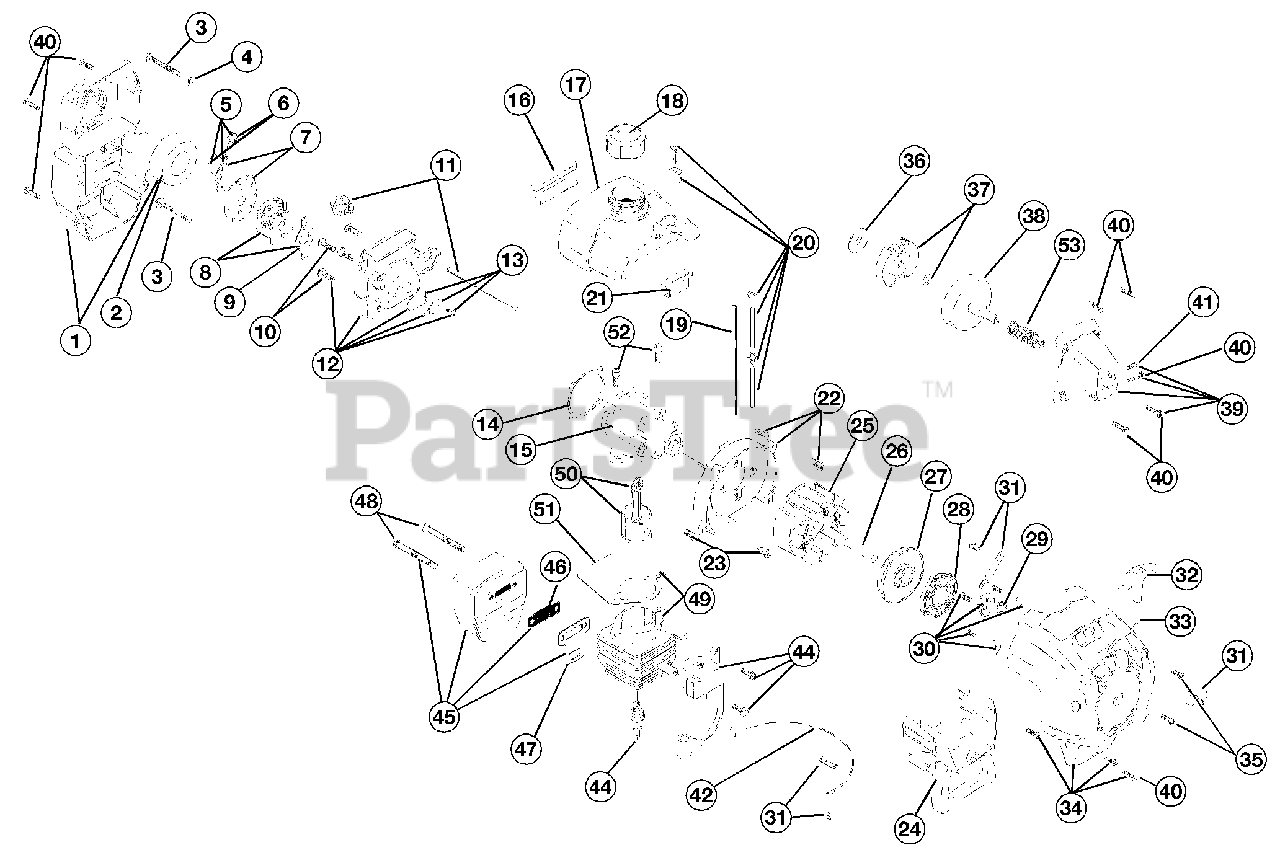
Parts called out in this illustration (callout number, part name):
1	Air Cleaner/Muffler Cover Assembly
2	Air Cleaner Filter
3	Carburetor Mounting Screw Assembly
4	Wavey Washer
5	Choke Lever Assembly
6	Choke Knob and Screw
7	Choke Lever and Plate
8	Carburetor Assembly
9	Carburetor Gasket
10	Carb Mount Screw
11	Primer and Hose Assembly
12	Carb Mount Assembly
13	Reed Assembly
14	Carburetor Mount Gasket
15	Crank Case Service Assembly
16	Rear Mounting Pad
17	Fuel Tank Assembly
18	Fuel Cap Assembly
19	Fuel Return Line
20	Fuel Line Assembly
21	Front Mounting Pad
22	Shroud Assembly
23	Shroud Screw
24	Shroud Extension and Stand
25	Flywheel Assembly
27	Recoil Pulley Assembly
28	Recoil Spring
29	Rope Guide
30	Pulley Retainer Assembly
31	Switch Assembly
32	Pull Handle
34	Starter Housing Assembly
35	Housing Screw
36	Clutch Washer
37	Clutch Rotor Assembly
38	Clutch Drum Assembly
39	Clutch Cover Assembly
40	Cover Screw
41	Anti-Rotation Screw
42	Wire Lead
43	Module Assembly
44	Spark Plug
45	Muffler Assembly
46	Spark Arrestor Screen
47	Exhaust Gasket
48	Muffler Mounting Bolt Assembly
49	Cylinder Assembly
50	Piston and Rod Assembly
51	Cylinder Gasket
52	Cylinder Bolt
